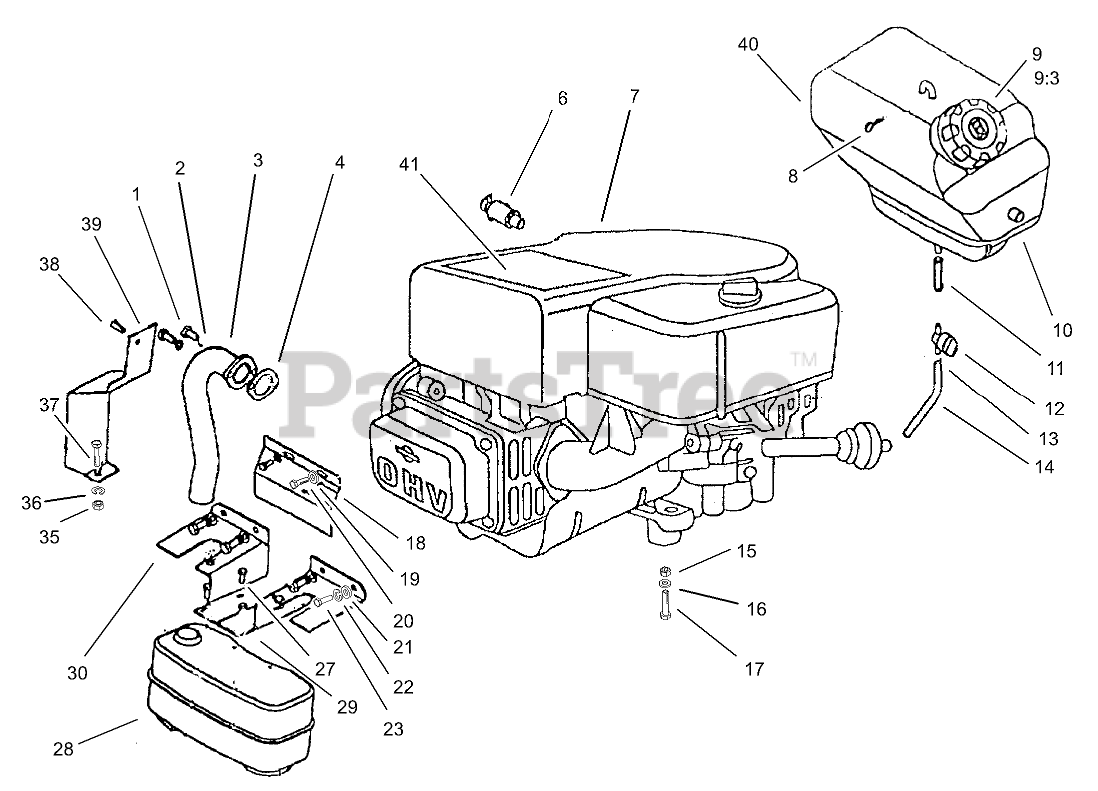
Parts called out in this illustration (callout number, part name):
1	SCREW-HH
2	WASHER-SPRING
3	TUBE-EXHAUST
4	GASKET-EXHAUST
6	VALVE-OIL DRAIN
8	PIN-HAIR
9	GAS CAP ASM
9:3	GASKET-CAP, GAS
10	TANK-FUEL
11	LINE-FUEL
12	VALVE-TANK, FUEL
13	CLAMP-LINE, FUEL
14	LINE-FUEL
15	NUT-LOCK, NI
16	WASHER-PLAIN
17	BOLT-HHF
17	SCREW
18	COVER-FRONT
19	WASHER-FLAT
20	SCREW-HWH
21	WASHER-FLAT
22	WASHER-SPRING
23	SCREW-HH
27	SCREW-HWH
28	MUFFLER
29	GUARD-MUFFLER, LH
30	GUARD-MUFFLER, RH
35	NUT-HEX
36	WASHER-SPRING
37	SCREW-HH
38	SCREW-HWH
39	COVER-EXHAUST MANIFOLD
40	TANK-FUEL W/CAP
41	DECAL-ENGINE 17HP
